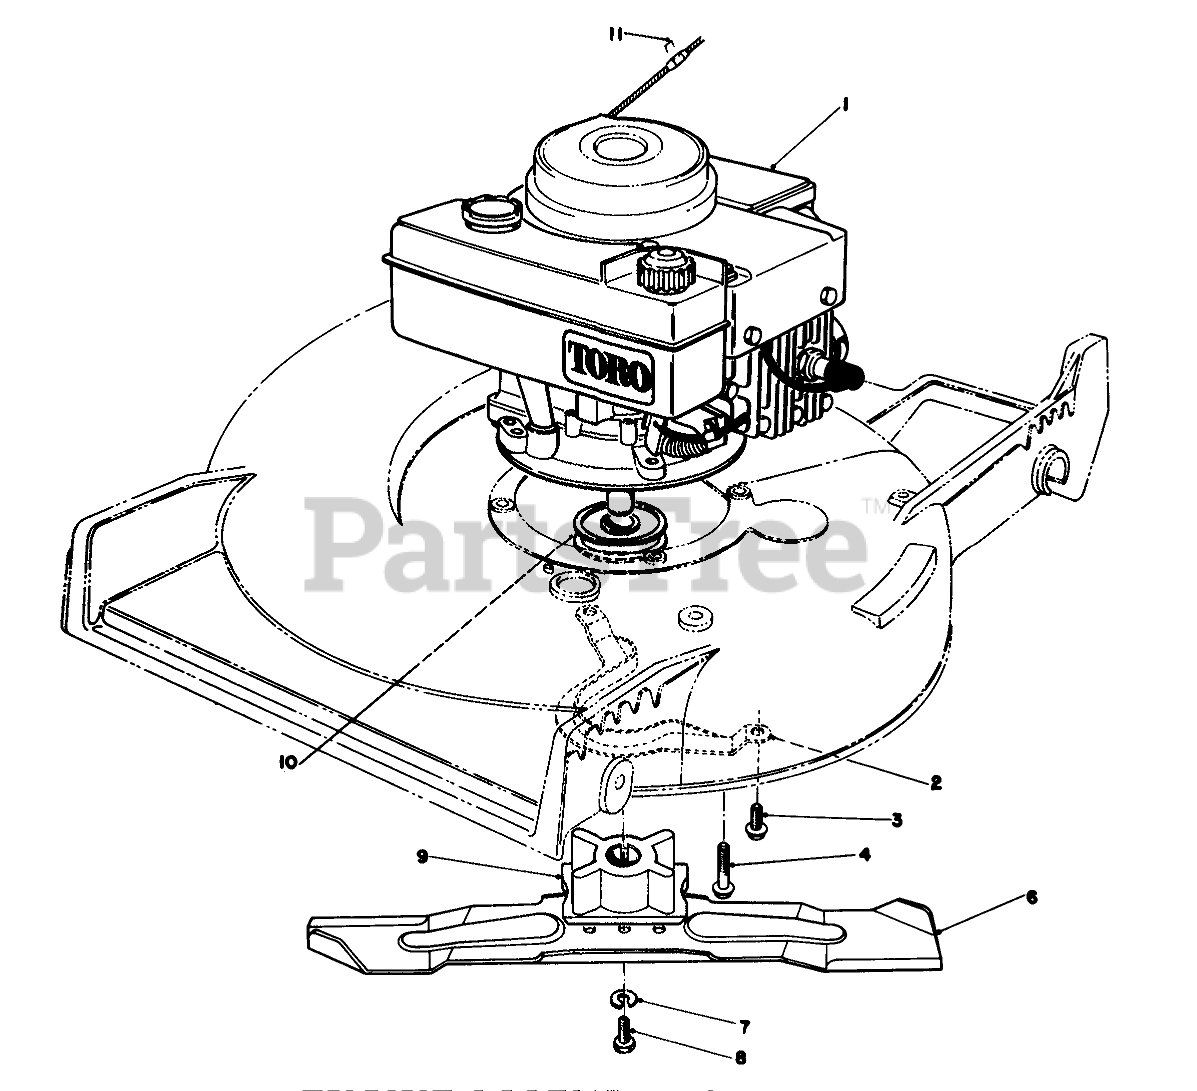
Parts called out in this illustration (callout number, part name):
2	BELT GUIDE
3	SCREW-HWHTF
4	3/8-16 X 2 CAPSCREW
6	BLADE-21in
7	WASHER-LOCK
8	SCREW-BLADE
9	BLADE RETAINER
10	PULLEY-DRIVE, ZONE START
11	Staple
